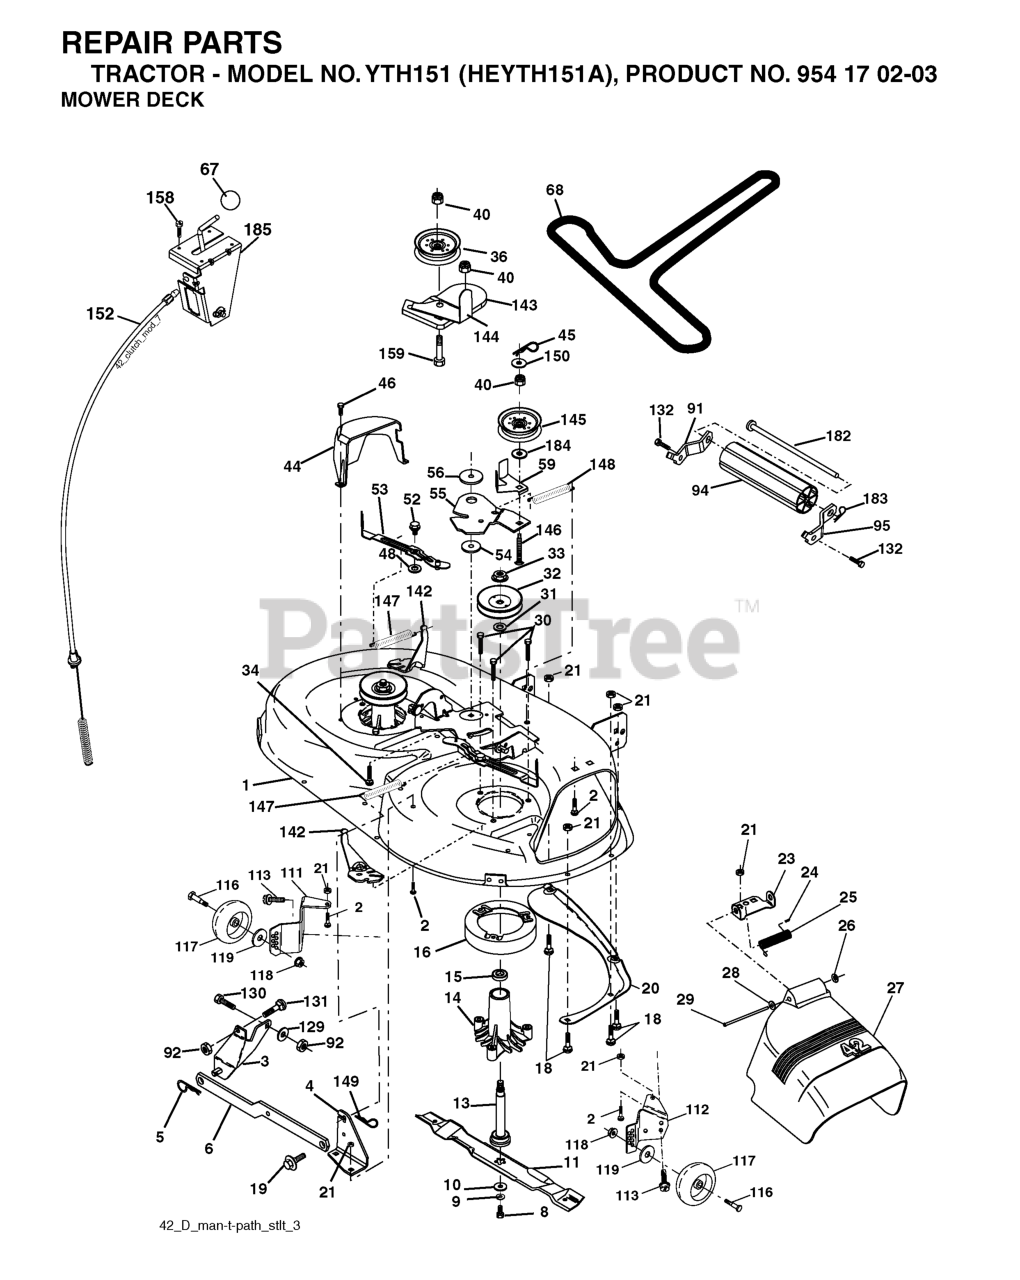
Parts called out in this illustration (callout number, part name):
1	42" DECK KIT
2	RP BOLT 5/16-18 X3/4 ZN/YEL GR
3	BRKT ASM SWAY BAR
4	BRACKET SWAY BAR 42" DECK
5	RETAINER-SPRNG RB
6	BAR SWAY DECK
8	BLADE BOLT
9	LOCKWASHER
10	WASHER.BLADE
11	42" HI-LIFT BLADE
13	SHAFT ASM VENT
14	HOUSING.MANDREL.VENTED (MACHD)
16	STRIPPER.MANDREL.ROUND.BLACK
18	BOLT
19	BOLT SHD 5/16-18
20	BAFFLE.VORTEX
21	LOCKNUT
23	BRKT, DEFL. MOWER
24	CAP-SLEEVE LT
25	SPRING TORSION
26	NUT PUSH M
27	SHIELD DEFLECTOR
28	Washer 11/32 x 5/8 x 16 Ga SD
29	ROD.HINGE
30	SCREW, WASHER HEAD
31	WASHER.SPACER.MANDREL
32	PULLEY/MANDREL
33	NUT, FLG TOPLOCK 9/16"
34	BOLT.3/8-16X1.50
36	FLAT IDLER PULLEY
40	NUT LOCK FLG 3/8-16 UNC
44	GUARD MANDREL LH BLACK
45	RETAINER M
46	SCREW.1/4-20X5/8
52	BOLT.SHOULDER.5/16-18
53	ARM BRAKE ASSY
55	ARM IDLER 42" MOWER LT/YT
56	SPACER.RETAINER.MOWER
59	GUARD, BELT
67	KNOB T (3/8 HOLE)
91	BRACKET ASM NOSEROLLER LH
92	NUT
94	NOSE ROLLER
95	BRACKET ASM NOSEROLLER RH
111	BRACKET, WHEEL
112	BRACKET, WHEEL
113	BOLT.5/16HEX.WHS.HD
116	BOLT M
117	WHEEL.GAUGE.STANDARD
118	LOCKNUT
119	WASHER.5/16.FLAT.STE.STD.
129	WASHER
130	BOLT
131	BOLT D
132	SCREW, 3/8-16X3/4
142	ARM SPRING BRAKE MOWER
143	BRACKET, ARM IDLER
144	DNO KEEPER.BELT.42".CLUTCH.CBL
145	PULLEY
146	BOLT, CARRIAGE IDLER BLACK
148	IDLER RETURN SPRING
149	SPRING.RETAINER.YELLOW.ZINC
150	WASHER LT
151	BRACKET.CLUTCH.CABLE
152	CABLE.CLUTCH.42"
153	WASHER FLAT 3/8"
154	SPRING RETAINER
155	SPRING RETENTION LEVER
156	SPACER.CLUTCH.CABLE
157	ROD CLUTCH CABLE 3/8"
158	SCREW
159	BOLT
182	ROD ROLLER NOSE STANDARD
183	SPRING RETAINER
184	WASHER
185	HEAD ASM. CABLE CLUTCH
